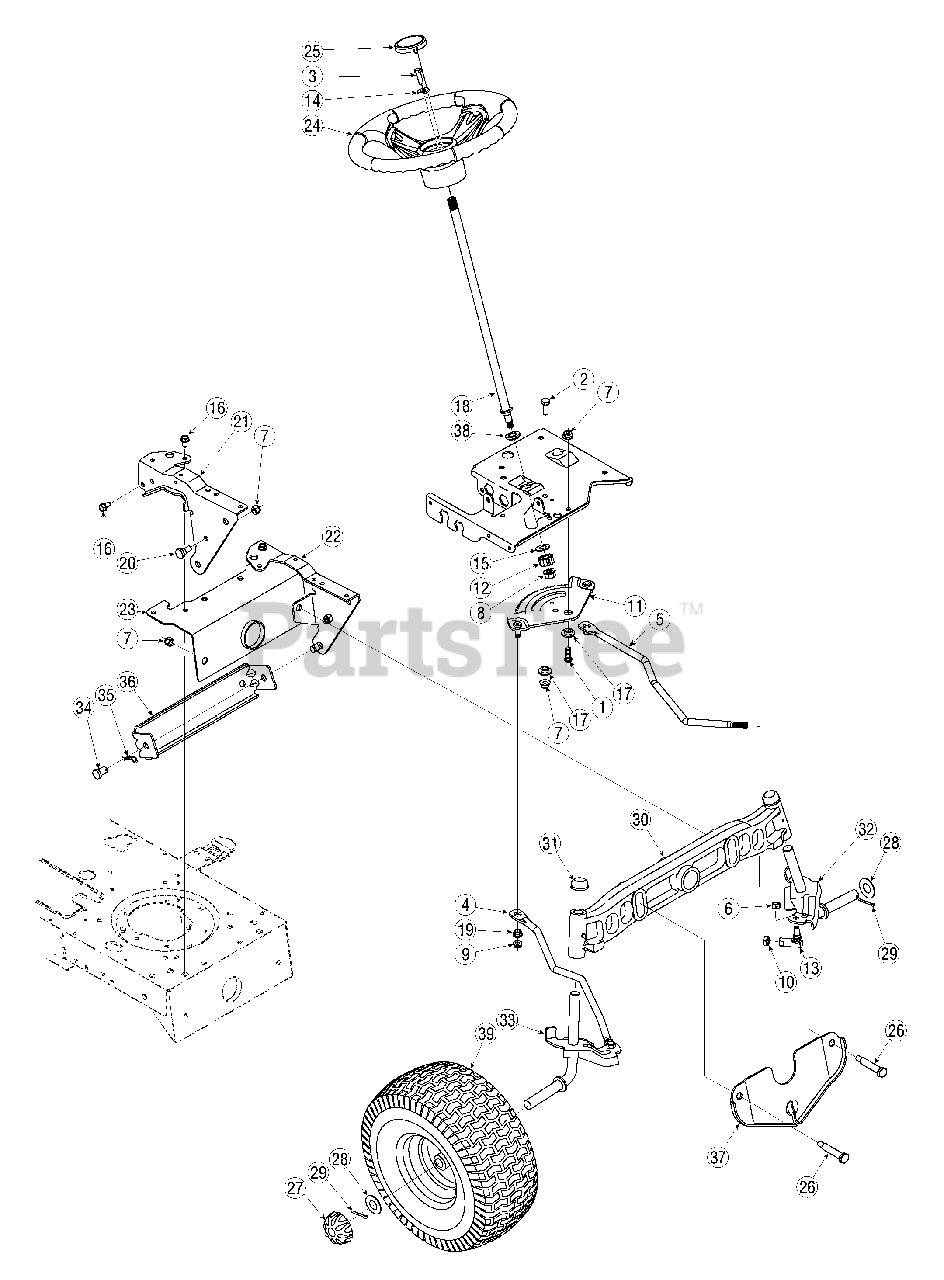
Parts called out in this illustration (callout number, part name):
1	Hex Screw, 3/8-16, 1.00, Gr5
2	Hex Screw, 3/8-16, 1.00, Gr5
3	Hex Screw, 5/16-18, 1.00, Gr5
4	Link, Drag, RH
5	Link, Drag, LH
6	Nut, Hex Lock, 3/8-24
7	Nut, Flange Lock, 3/8-16, Grf, Nylon
8	Nut, Flange Lock, 7/16-20
9	Nut, Flange Lock, 5/16-18, Gr5
10	Nut, Jam, 7/16-20, Gr2
11	Gear, Steering, 11/90 Ratio
12	Gear, Pinion, Steering
13	Ball Joint, 7/16-20, Lock
14	Washer, Flat,.406 x.875 x.105
15	Washer, Flat,.51 x 1.12 x.06
16	Screw, 5/16-12, 0.750
17	Spacer, Shoulder,.38 x 1.00 x.31
18	Shaft, Steering,.625 OD x 24.25 Lg
19	Plastic Bushing.380 ID
20	Screw, Shoulder,.498 x.340, 3/8-16
24	Steering Wheel
25	Steering Wheel Cap
26	Shlder Screw,.5 x 2.380, 3/8-16 (42H)
27	Deluxe Hub Cap
28	Flat Washer,.78 x 1.589 x.06
29	Cotter Pin, 5/32 x 1.25
30	Cast Iron Pivot Bar
31	Push Cap
32	LH Axle Assembly,.750 (42H)
33	RH Axle Assembly,.750 (42H)
34	Pin, Clevis,.50 x.78 (46H)
35	Cotter Pin, Inter,.080 x 1.5625 (46H)
38	Hex Flange Bearing
